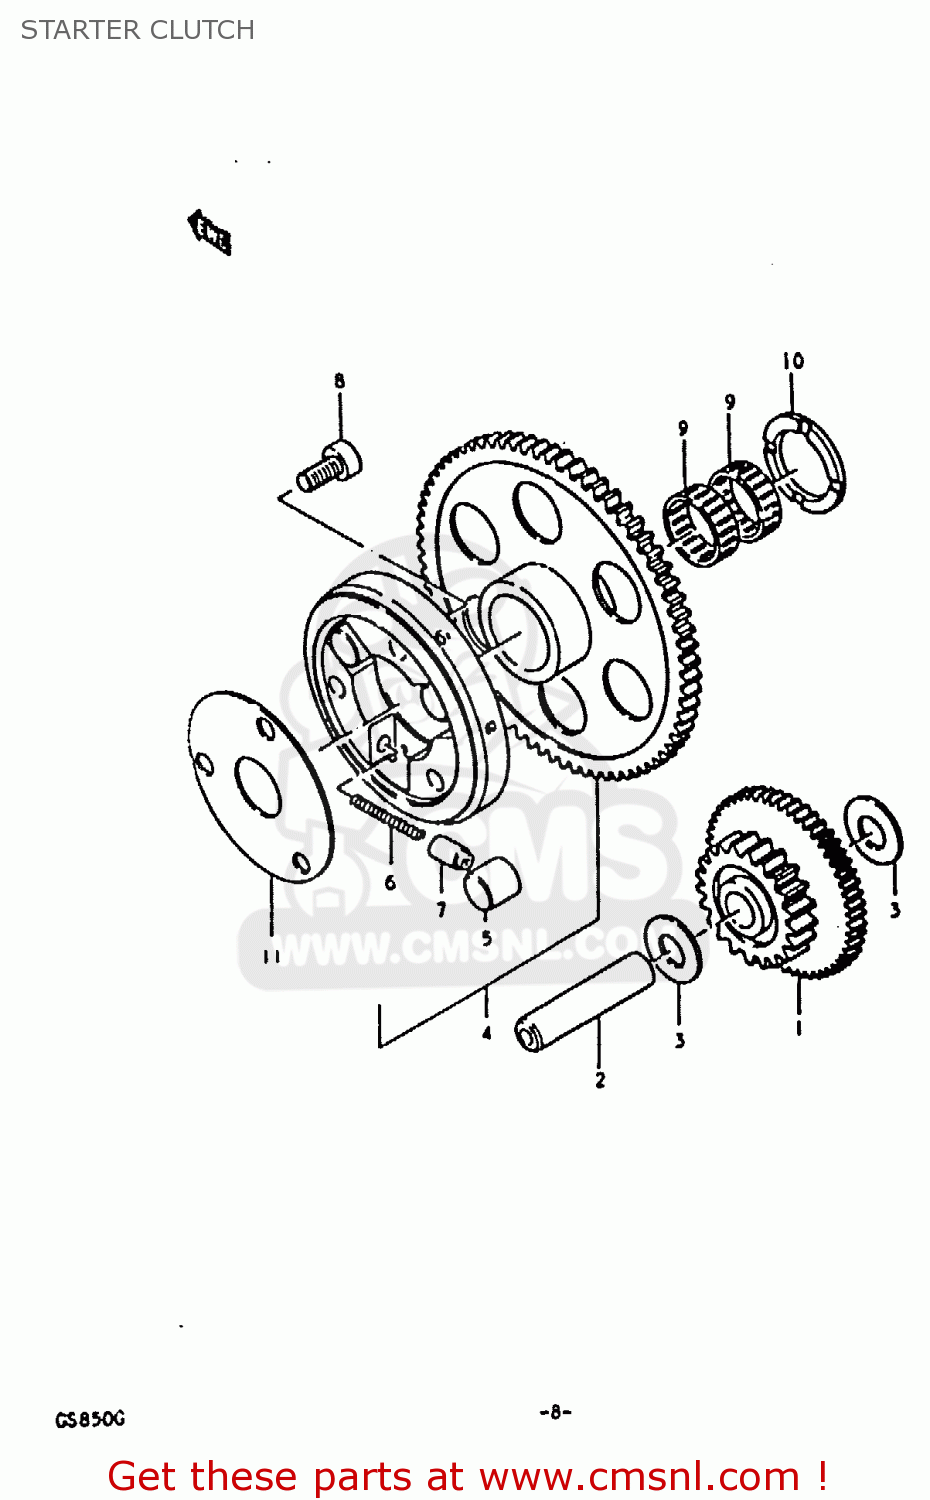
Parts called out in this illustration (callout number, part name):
1	GEAR,STARTER IDLE
2	PIN(7.4X13X56)
3	WASHER(13.3X25X0.85)
4	CLUTCH SET,STARTER
5	ROLLER(15X13)
6	SPRING
7	PIECE,PUSH
8	BOLT
9	BEARING(25X29X9.9)
10	WASHER(25X38X2.5)
11	SHIM,STARTER CLUTCH HUB
